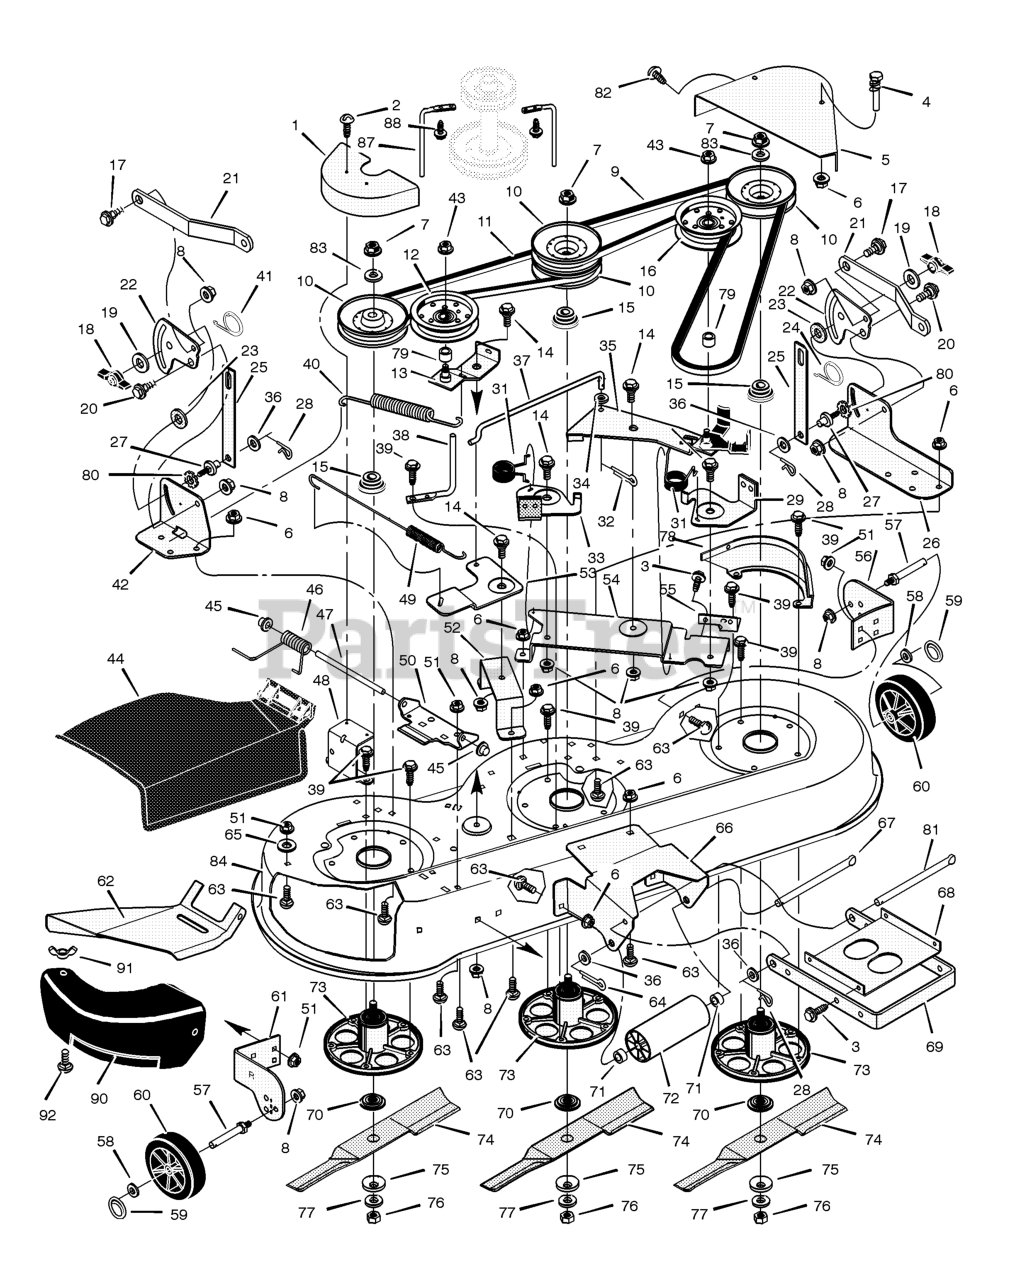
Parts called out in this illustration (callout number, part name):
1	Cover, Right Pulley
2	Screw
4	Guide, Belt
5	Cover, Left Pulley
6	Nut, Hex
7	Nut, Flange
8	Nut, Flange
9	Belt, Primary
10	Pulley
11	Belt, Secondary
12	Pulley, Idler
13	Arm, Idler
14	Bolt, Shoulder
15	Spacer, Pulley
16	Pulley, Idler
17	Bolt, Shoulder
18	Knob
20	Bolt, Shoulder
21	Bracket, Rear Suspension
22	Plate, Suspension
23	Pad, Friction
25	Link, Lift
26	Bracket, Left Lift
27	Pin, Hanger
28	Pin, Hair
29	Brake Assembly, Left
32	Pin, Cotter
33	Brake Assembly, Right
34	Washer
35	Idler, Arm
37	Link, Bell Crank
38	Guide, Belt
39	Screw
40	Spring, Extension
41	Spring, Torsion
42	Bracket, Suspension
43	Nut
44	Deflector, Chute
45	Push On Cap
46	Spring, Torsion
47	Rod, Deflector
48	Bracket, Cover
49	Spring, Extension
50	Bracket, Hinge
51	Nut, Flange
52	Bracket, Bell Crank
53	Crank, Bell
54	Plate, Brake Arm
55	Bracket, Brake Plate
56	Bracket, Left Gauge Wheel
57	BOLT, Gauge Wheel
59	Ring, Locking
60	Wheel, Gauge
61	Bracket, Right Gauge Wheel
62	Deflector, Inside
63	Bolt, Carriage
64	Pin, Cotter
66	Bracket, Front Deck
67	Rod, Hanger
68	Stiffener
69	Bracket, Suspension
70	Adapter, Blade
73	Housing, Jackshaft
75	Washer, Belleville
78	Bracket, Pulley Cover
81	Rod, Hanger
83	Washer
84	Housing, Blade
87	Guide, Belt
88	Screw
90	Cover, Mulch
91	Wingnut
92	Bolt, Carriage
